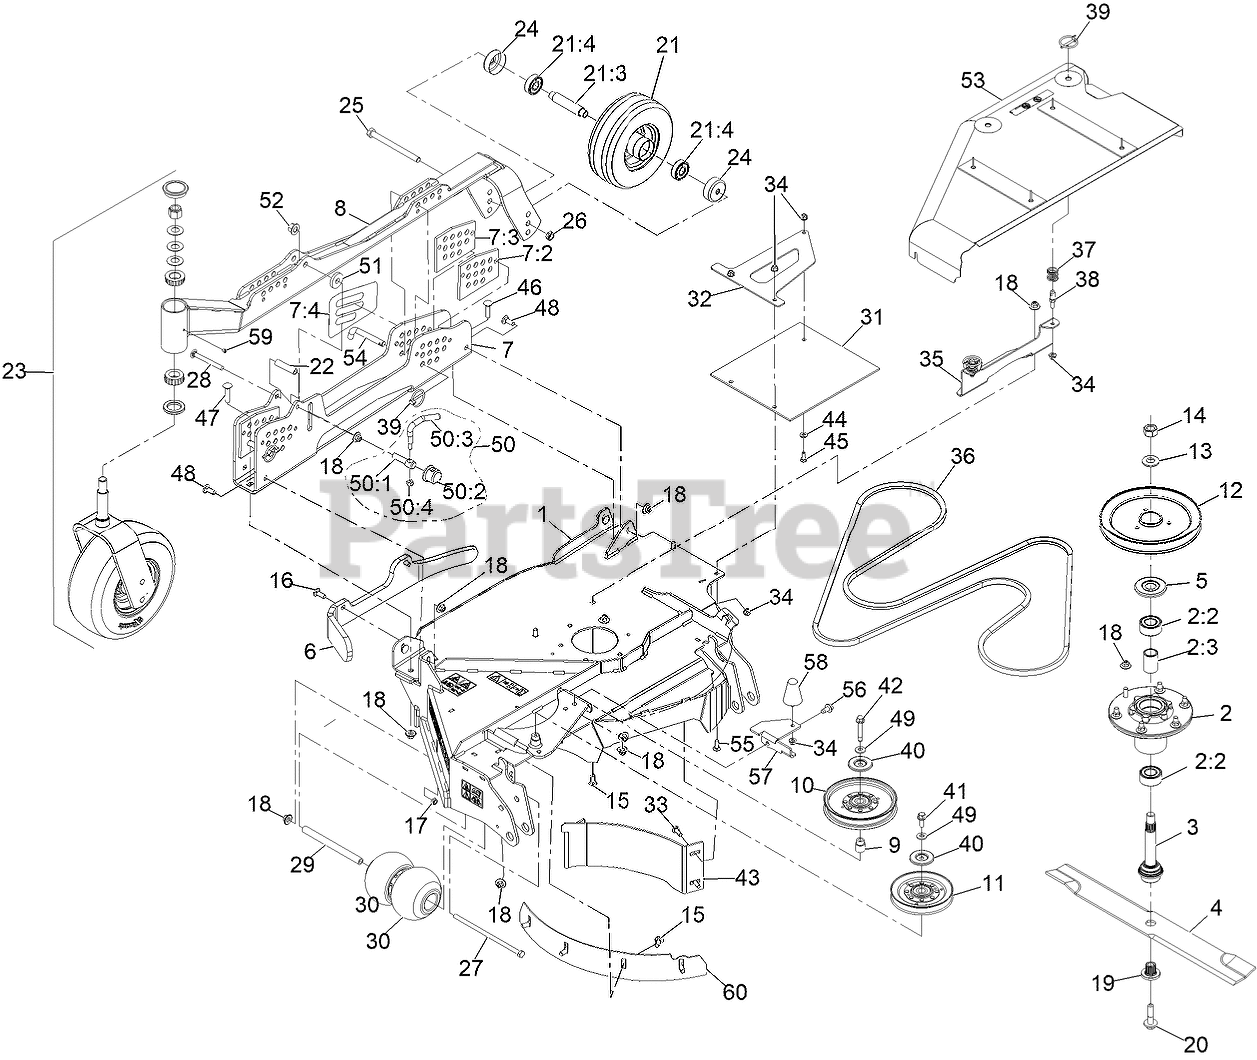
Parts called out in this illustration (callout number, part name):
1	ASM-DECK, RH WING 96
2	ASM-CUTTER HSG
2:2	BEARING-3205 TRASHGUARD
2:3	SPACER-BEARING
3	ASM-SPINDLE AND SEAL
5	GUARD-BEARING, TOP
6	BUMPER-96 RH
7	RH HOC CHANNEL ASM
7:2	PLATE-GUIDE, HOC (LH)
7:3	PLATE-GUIDE, HOC (RH)
7:4	DECAL-HEIGHT OF CUT, RH
8	CALL CUSTOMER SERVICE
9	BUSHING-IDLER
10	IDLER-PULLEY
11	IDLER-V
12	SHEAVE-SINGLE 96RD
14	NUT-HEX
15	BOLT-CARR
16	SCREW-CARR
18	Nut-Nyloc 3/8-16 Flg
19	BUSHING,SPLINED
20	SCREW,SEMS 1/2-20 X 2.19
21	WHEEL AND TIRE ASM
21:3	AXLE-CASTER
21:4	BEARING
24	GUARD, SEAL
25	SCREW-HH
26	NUT-HEX
27	SCREW-HH
28	SCREW-CARR
29	SPACER-WHEEL
30	ROLLER-SCALP, ANTI
31	GUARD-TIRE
32	SUPPORT-FLAP, RH
33	SCREW-CARR
34	NUT-HF, NI
35	BRACKET-SHIELD MOUNT, OUT
38	PIN, SPRING
39	PIN-LYNCH
40	SHIELD-DUST
41	SCREW-HHF 3/8-16 X 1
42	SCREW-HHF
43	BAFFLE-BLOCK, RH WING
44	WASHER-PLAIN
45	SCREW-HH
46	SCREW-CARR
47	SCREW-CARR
48	BOLT-CARR
49	WASHER-BELLEVILLE
50	LEVER ASM
50:1	SCREW-LOCK
50:2	CAP-LOCK
50:4	NUT-LOCK, NI
52	Nut-Lock 1/2-13
53	ASM-Wing Shield RH
54	PIN-HOC
55	BOLT-CARR
56	SCREW-HWH
57	BRACKET-COVER RETAINER
58	BUMPER-RUBBER
60	BAFFLE-DEPTH, RH
